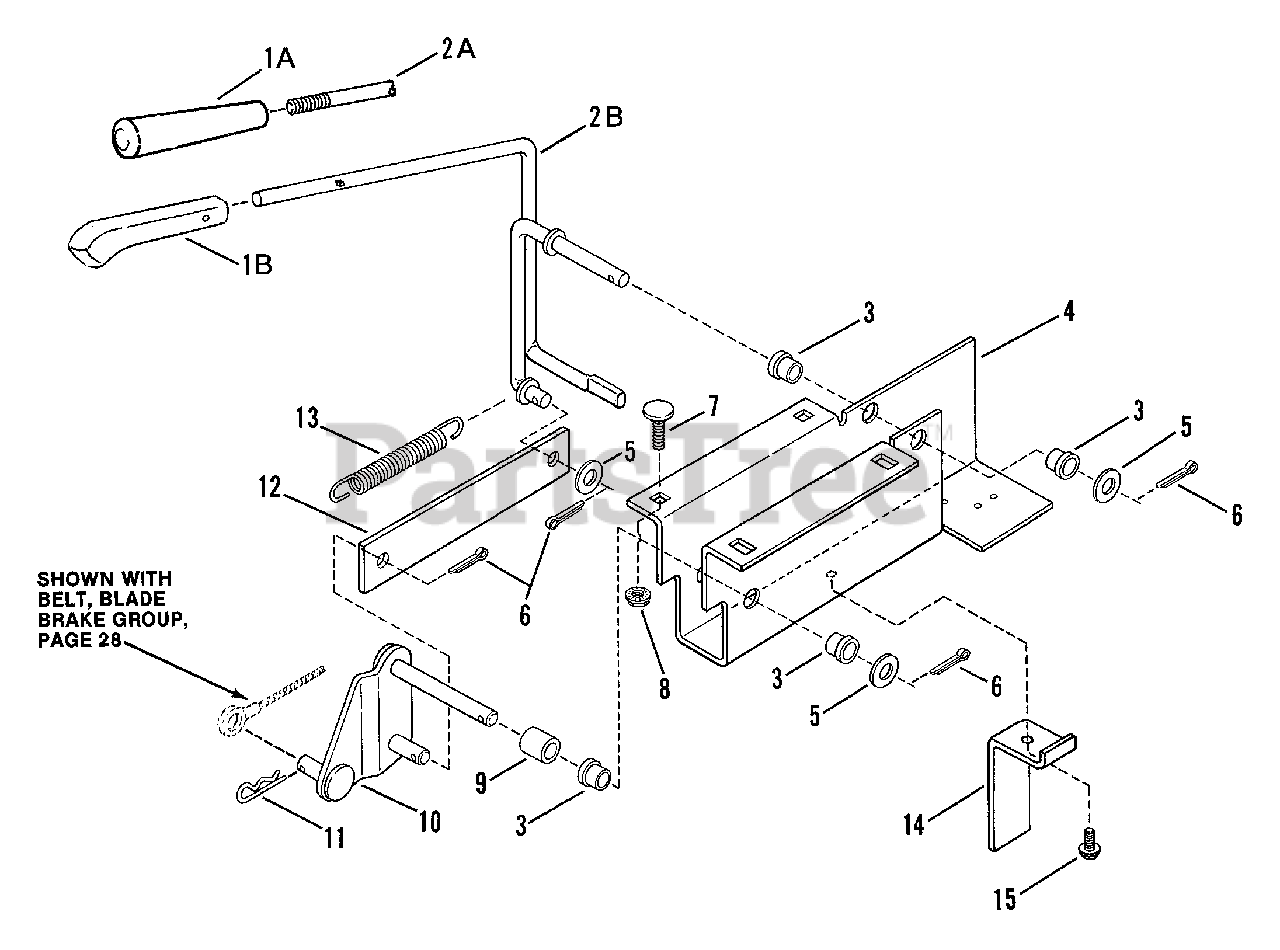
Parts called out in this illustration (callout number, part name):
1A	KNOB, Handle
1B	KNOB, Handle
2A	HANDLE, Blade Engagement (Threaded)
2B	HANDLE, Blade Engagement
3	BUSHING
4	BRACKET, Handle
5	WASHER
6	COTTER-PIN, 3/32x3/4" Flat Head Carriage
7	BOLT, 1/4-20x5/8" Flat Head Carriage
8	LOCKNUT, 1/4-20 Hex Flange
9	SPACER
10	PIVOT ARM ASSEMBLY
11	PIN, Hair
13	SPRING, Return
14	GUIDE, Belt
15	SCREW, #10-24x1/2" H.W.H.S.T.
